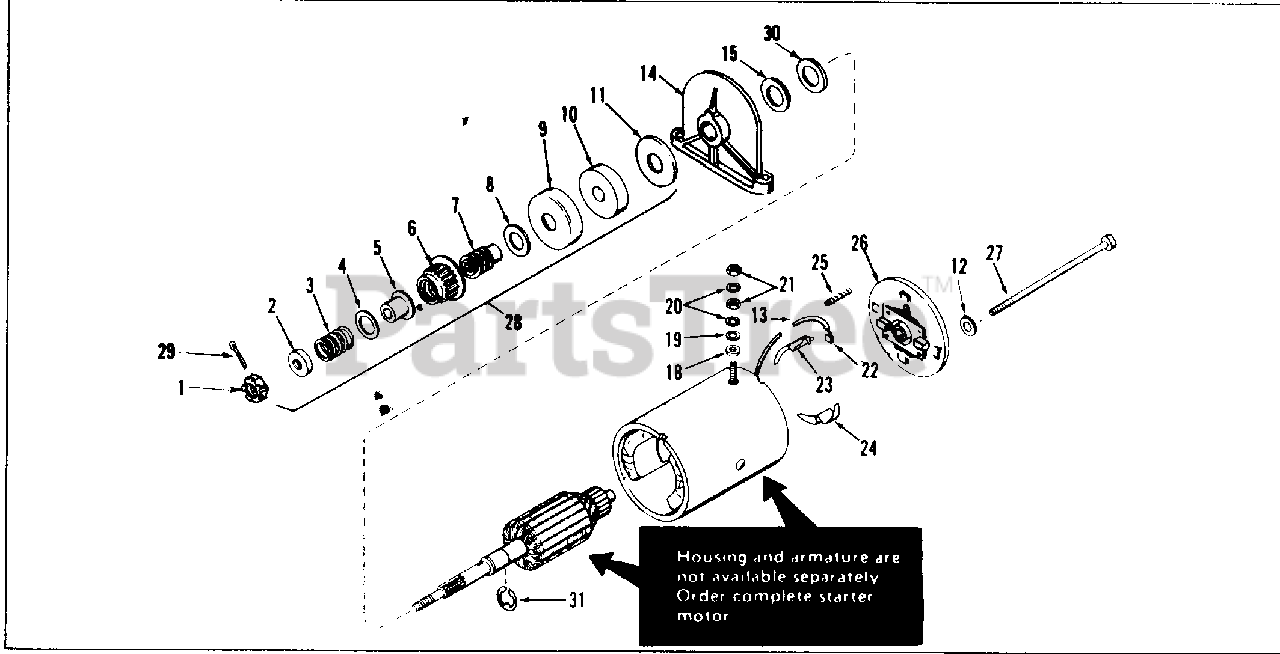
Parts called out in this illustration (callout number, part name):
1	"Nut, Castellated
2	Stop, Pinion
3	Spring, Anti-drift
4	Washer, Pinion
5	Sleeve, Anti-drift spring
6	Gear, Pinion
7	Shaft, Screw
8	Washer, Thrust
9	Cup, Cushion
10	Cushion Rubber
11	Washer, Thrust
12	Washer, Lock
13	Tubing, Insulation
14	Cap Assy., Drive end, includes bearin g
15	Washer, Spacing (.003 thick)
18	Washer, Insulation
19	Washer, Plain
20	Washer, Lock
21	Nut, Hex
23	Insulation
24	Insulation
25	Spring, Brush
26	End Cap Assy., Commutator
27	Bolt, Thru
28	Drive Assy.,Complete
29	Pin, Cotter
30	Washer, spacer (.010 thick)
31	Ring, Retaining
